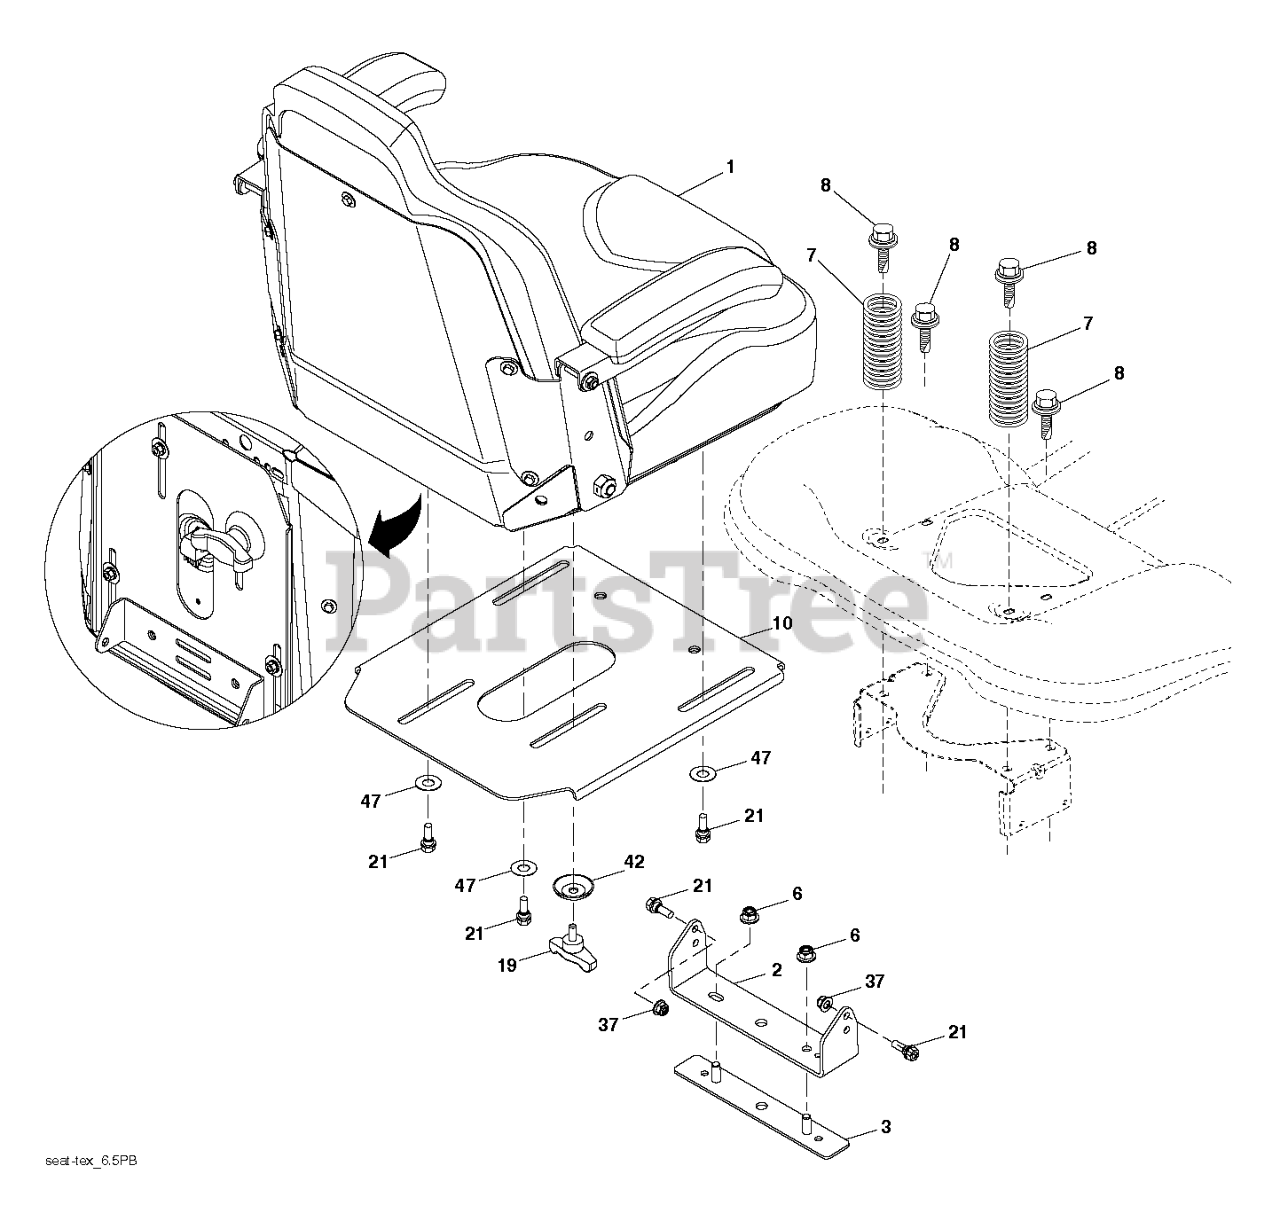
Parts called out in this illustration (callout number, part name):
1	SEAT ASSY TR193.ARMREST REDMAX
2	BRACKET PIVOT FENDER SEAT TRAC
3	BRACKET ASSEMBLY REINFORCEMENT
6	NUT 3/8-16 HEX FLG NYLOC ZD
7	SPRING.COMPRESSION.SEAT.BLACK
8	BOLT, 5/16-18 X 1 3/4
10	BRACKET ASM PLATE & BRACKET SE
19	KNOB SEAT 5/16-18X3/4
21	BOLT SHOULDER 5/16-18 UNC
37	5/16-18 NYLOC FLANGE NUT
42	WASHER.CUP.SEAT.
47	WASHER NYLON .50 X 1.00 X .045
